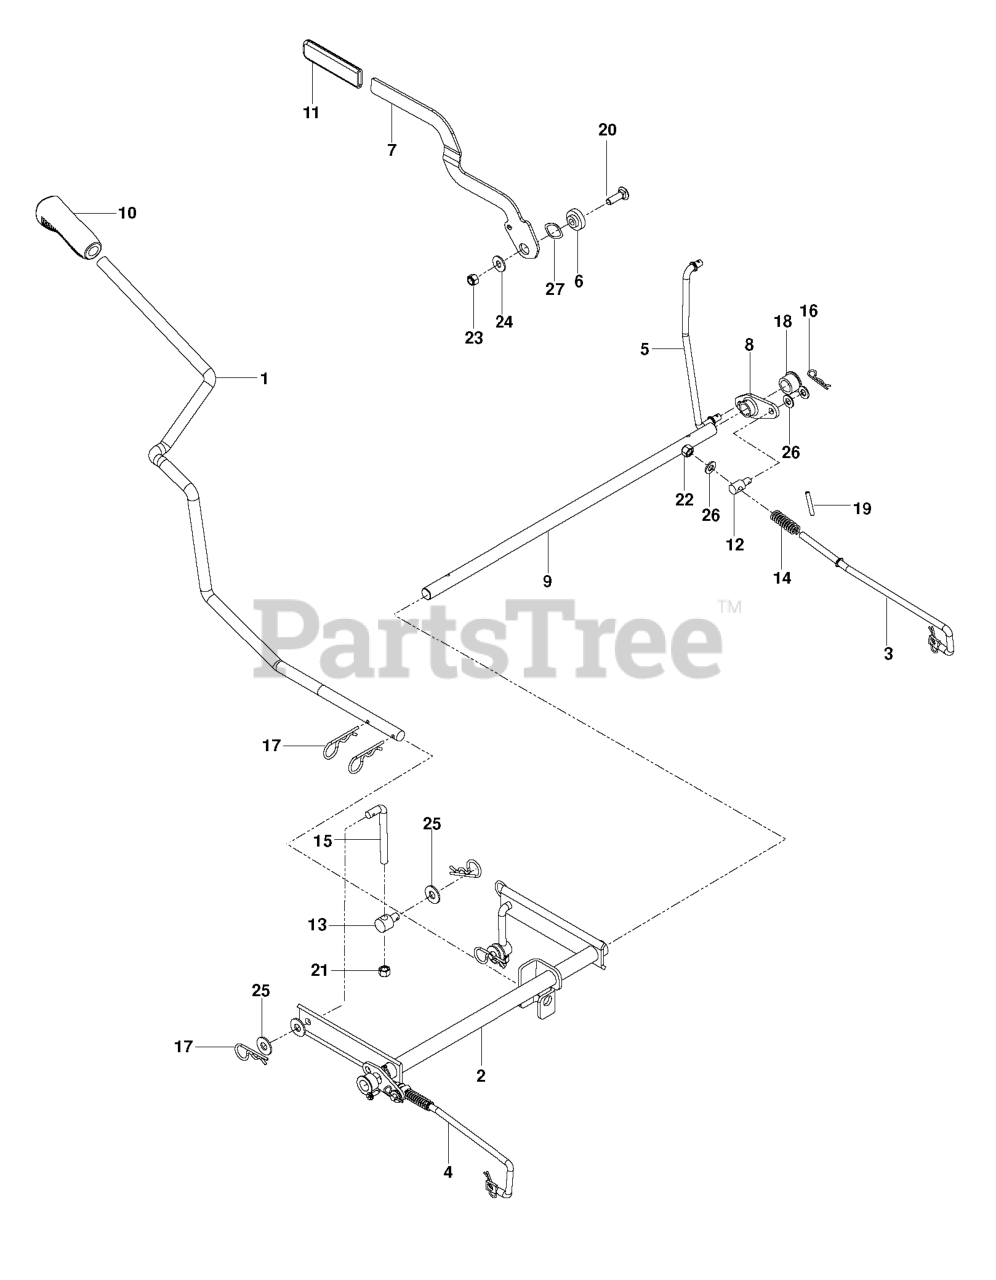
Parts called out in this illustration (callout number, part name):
1	ARM, LIFT HANDLE, BLK
2	SHAFT, LIFT WLDMT, BLACK
3	LINKAGE, EZT BRAKE RT
4	LINKAGE, EZT BRAKE LT
5	LINKAGE, BRAKE, UPPER
6	BRAKE ARM PIVOT
7	HANDLE, BRAKE, BLK
8	BELLCRANK, BRAKE
9	ROD, BRAKE
10	GRIP.LEVER.5625.ID
11	GRIP BRAKE HANDLE
12	BRAKE SWIVEL
15	L ROD 3-1/8"
16	HAIRPIN #2
17	HAIRPIN #4
18	PLASTIC BUSHING
19	ROLL PIN 3/16 X 1-1/4 ZD
20	RHSNB 3/8-16 X 1-1/4
21	NUT 3/8-16 NYLOC
22	NUT 5/16 NYLOC
23	NUT HEX 3/8-16 NYLON, THIN
24	WASHER, 7/16 DISC SPRING
25	WASHER 3/8 FLAT
26	FLAT WASHER 5/16 SAE
27	WASHER, .825 X 1.087, WAVE
